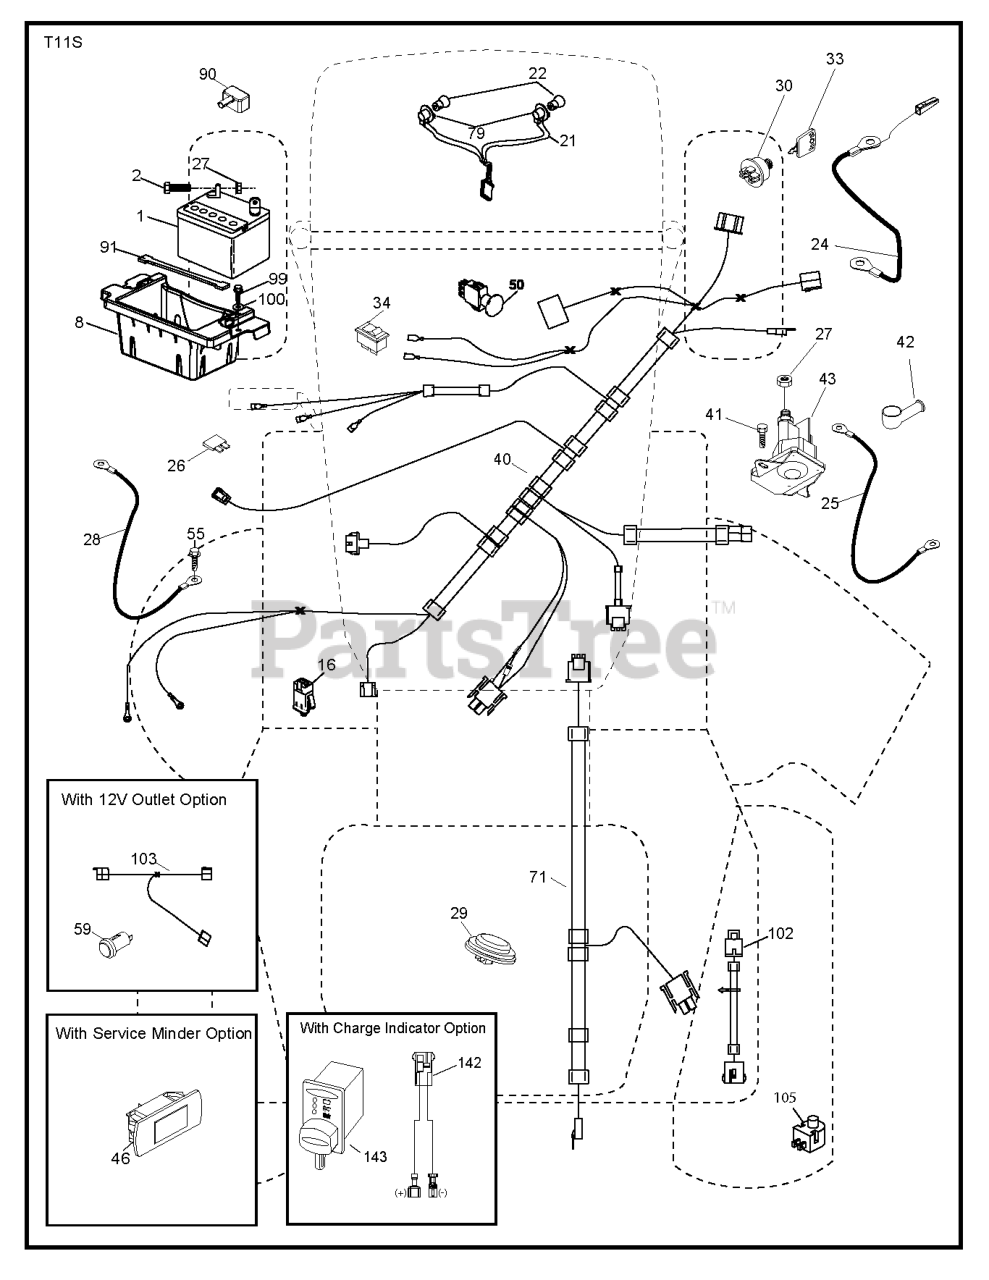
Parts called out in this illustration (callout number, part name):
1	Battery 12 Volt 25 Amp
2	BOLT.HEX.1/4.X.3/4.DICHROMATE
8	BOX.BATTERY.MOUNT.FRONT.LT
16	SWITCH INTERLOOK PUSH-IN
21	HARNESS.LIGHT W/4152J BULBS
24	CABLE.BATT.POS.WIRE.TG.DA SOL
25	CABLE.STARTER.6G.BL/RED.17.5
26	FUSE 20AMP
27	NUT
28	CABLE GROUND 6 GA 21" 90T BLK
29	SWITCH.SEAT.DELTA.OPC.
30	SWITCH.IGN.DELTA.W.LGH.ROS
33	KEY.CHAIN.BLISTER.PACK.GEN.USA
40	HARNESS.IGN.DASH.HUQ/P
41	SCREW
42	TERMINAL COVER
43	SOLENOID.W/BRASS.PLUNGER
46	RP.GUAGE.SRVCMNDR.HRMTR.
50	RP.SWTICH.PTO.8.TERMINAL
55	SCREW 5/16"
71	HARNESS-CHASSIS SUB
79	BULB HOLDER ASM.
90	COVER.TERMINAL.BATTERY
91	STRAP.BATTERY.MOUNT.FRONT(2 2)
99	SCREW HEXWSHR 1/4-20X3/4
102	HARNESS PIGTAIL PCH TEX ROS
105	REVERSE SWITCH
